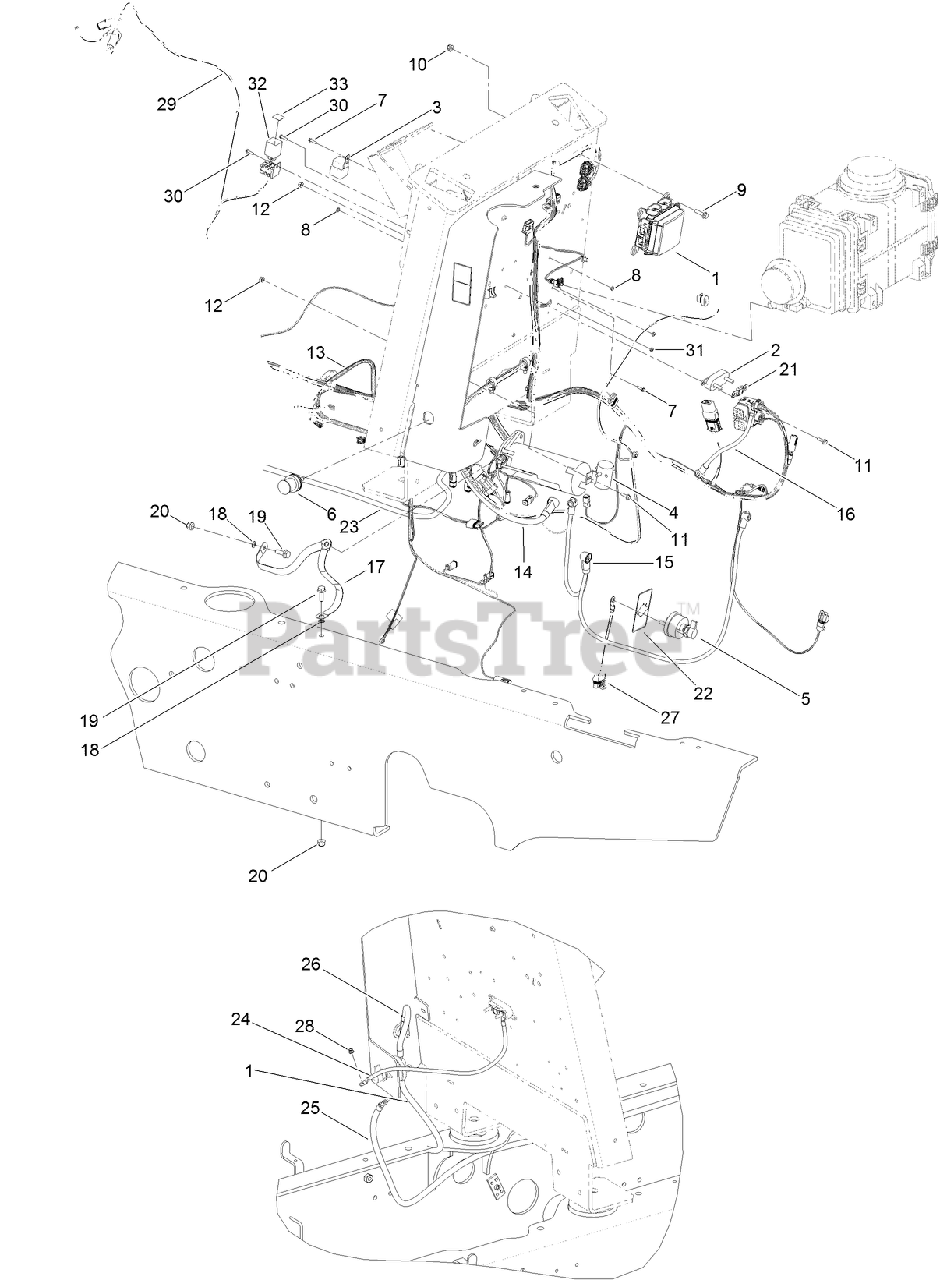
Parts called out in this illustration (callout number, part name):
1	BOX-VEHICLE, MAIN
2	HOLDER-FUSE
3	RELAY
4	SOLENOID-RELAY 12V, 300A
5	SWITCH-DISCONNECT, MASTER
6	POST-BATTERY, REMOTE
7	SCREW-HWH
8	NUT-LOCK, NI
9	SCREW-HHF
10	NUT-LOCK, HHF
11	SCREW-HHF
12	NUT-HHF
13	HARNESS-MAIN
14	CABLE-BATTERY, POSITIVE
15	CABLE-BATTERY, POSITIVE
16	CABLE-BATTERY, POSITIVE
17	STRAP-GROUNDING
18	WASHER-LOCK
19	SCREW-HHF
20	NUT-LOCK, NI
21	FUSE-250 AMP
22	DECAL-DISCONNECT, BATTERY
23	CABLE-BATTERY, POSITIVE
24	CABLE-BATTERY, POSITIVE
25	CABLE-BATTERY, NEGATIVE
26	CABLE-BATTERY, POSITIVE
27	HARNESS-WIRE, FUSIBLE LINK
28	NUT-HHF
29	HARNESS-WIRE, HYDRAULIC BYPASS
30	SCREW-HWH
31	NUT-LOCK, NI
32	RELAY-ADJUSTABLE REL 12V
33	DECAL-COVER
